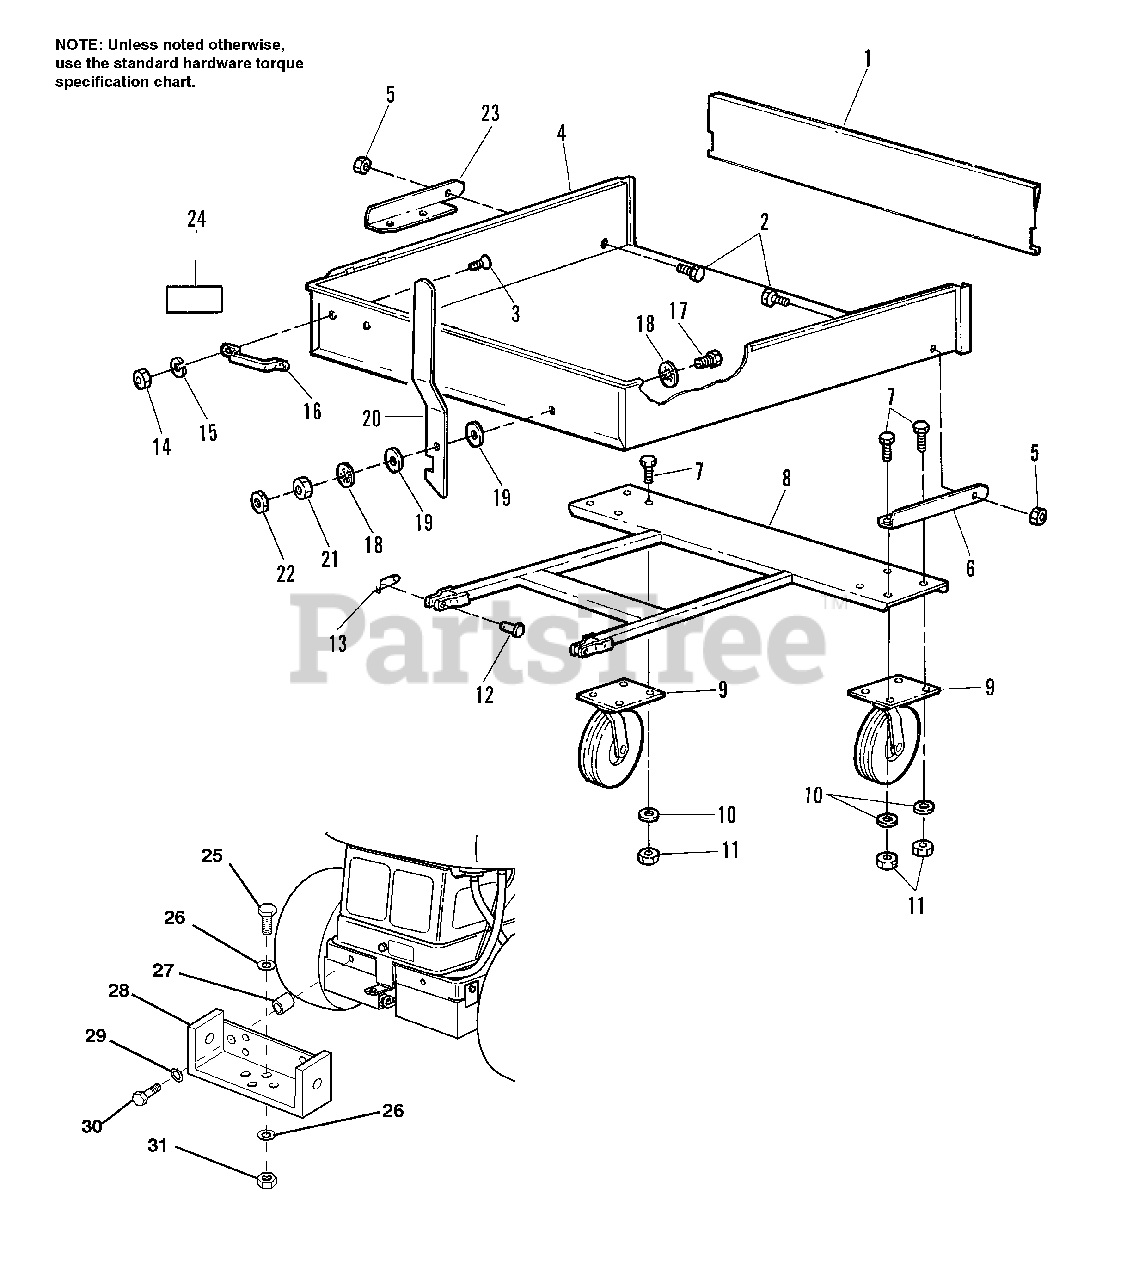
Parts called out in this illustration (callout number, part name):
2	CAPSCREW, 1/2-13 x 1
3	CAPSCREW, Hex, 1/4-20 x 1/2
5	LOCKNUT, Hex, Flange, 1/2-13
6	BRACKET, Pivot, L.H.
7	CAPSCREW, Hex, 3/8-16 x 1
9	WHEEL, Swivel
10	WASHER, 3/8
11	NUT, Hex, Lock, 3/8-16
12	PIN, Clevis, 1/2 x 1-1/2
13	PIN, Safety
14	NUT, Hex, 1/4-20
15	LOCKWASHER, 1/4
16	HANDLE, Lift
17	CAPSCREW, 5/16-18 x 1-1/4
18	WASHER, 5/16
19	WASHER, Spring, 5/16
20	HANDLE, Latch
21	NUT, Hex, Full, 5/16-18
22	NUT, Hex, Jam, 5/16-18
23	BRACKET, Pivot, R.H.
24	DECAL, Max. Capacity
25	Capscrew, 3/8-16 x 1
26	Flat Washer, 3/6
28	Hitch
29	Lockwasher, 3/8
30	Capscrew, 3/8-16 x 2-1/4
31	Hex Nut, 3/8-16
